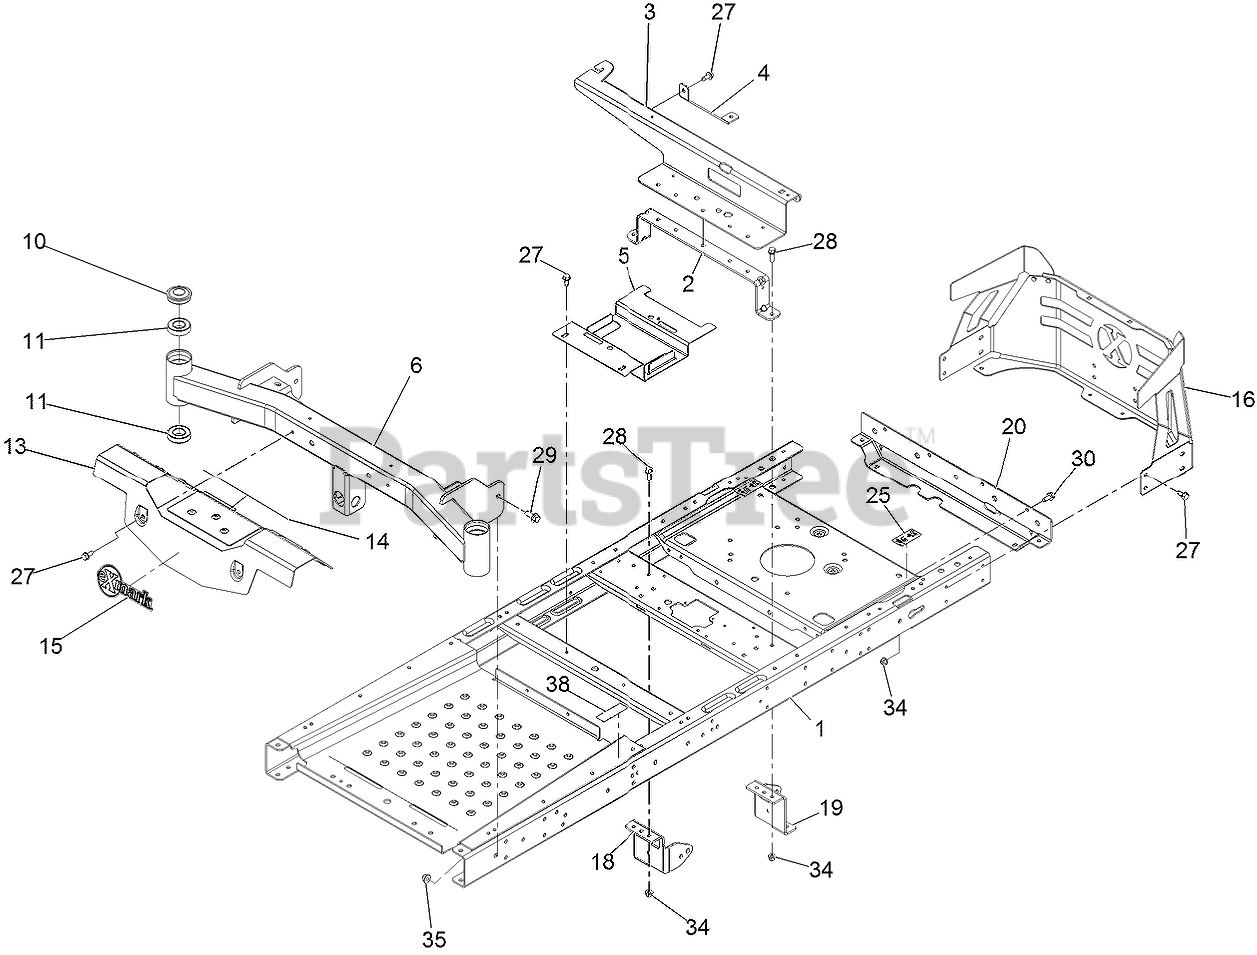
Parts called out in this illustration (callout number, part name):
1	RIVETED FRAME ASM (WIDE LEVER)
2	BRACE-SEAT, REAR (WIDE)
3	SUPPORT-POD
4	SUPPORT-TANK, REAR
5	BRACKET-BATTERY
6	AXLE-FRONT 50
10	Cap-Grease
11	BEARING-BALL
13	FOOTREST ASM
14	DECAL-WARNING
15	DECAL, EXMARK LOGO
16	GUARD-ENGINE, ASM WIDE
18	MOUNT-HYDRO, FRONT (RIGHT
19	Mount-Hydro, Front (Left)
20	CROSSMEMBER-REAR, WIDE
25	DECAL-BYPASS
27	Screw-HWH 5/16-18 X 3/4 Tf
28	SCREW-HHF
29	SCREW-HHF 3/8-16 X 1
30	SCREW-HHF
34	NUT-HF, NI
35	NUT-HF, NI
38	DECAL-BRAKE, PARKING
